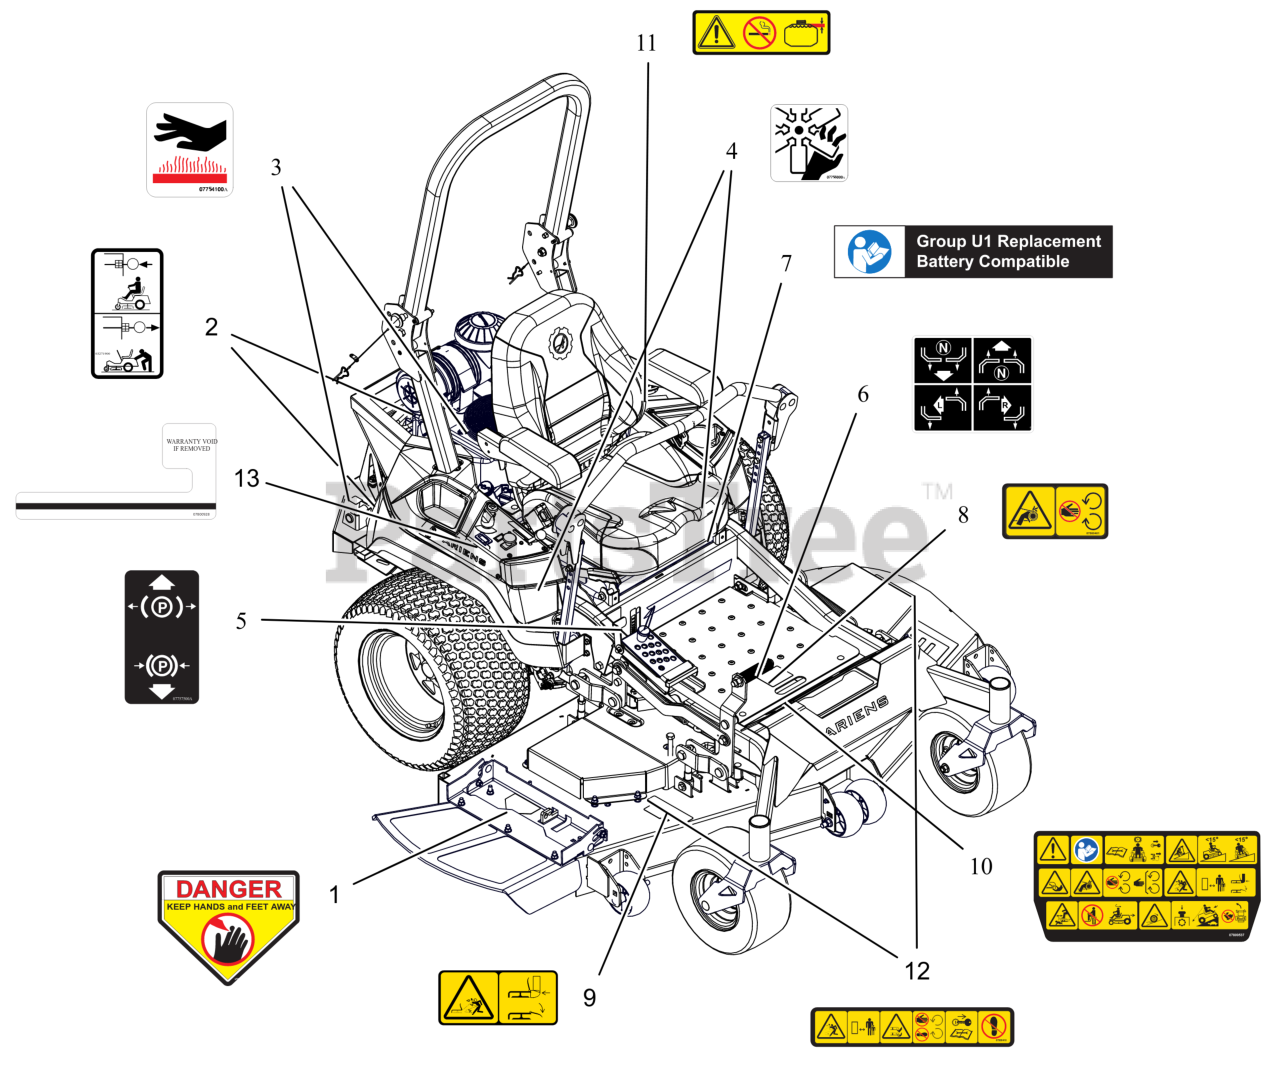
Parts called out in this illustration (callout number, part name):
1	DECAL, DANGER
2	DECAL, TRANSMISSION DISCONNECT
3	DECAL, HOT SURFACE
4	DECAL, DANGER FAN
5	DECAL, PARKING BRAKE LEVER
6	DECAL, INSTRUCTIONAL-STEERING
7	DECAL, U1 BATTERY REPLACEMENT
8	DECAL, SAFETY - GUARDING
9	DECAL, SAFETY - DECK GUARDING
10	DECAL, MAIN SAFETY
11	DECAL, FUEL WARNING
12	DECAL, DECK SAFETY
13	DECAL,HOURMETER - SECURITY
